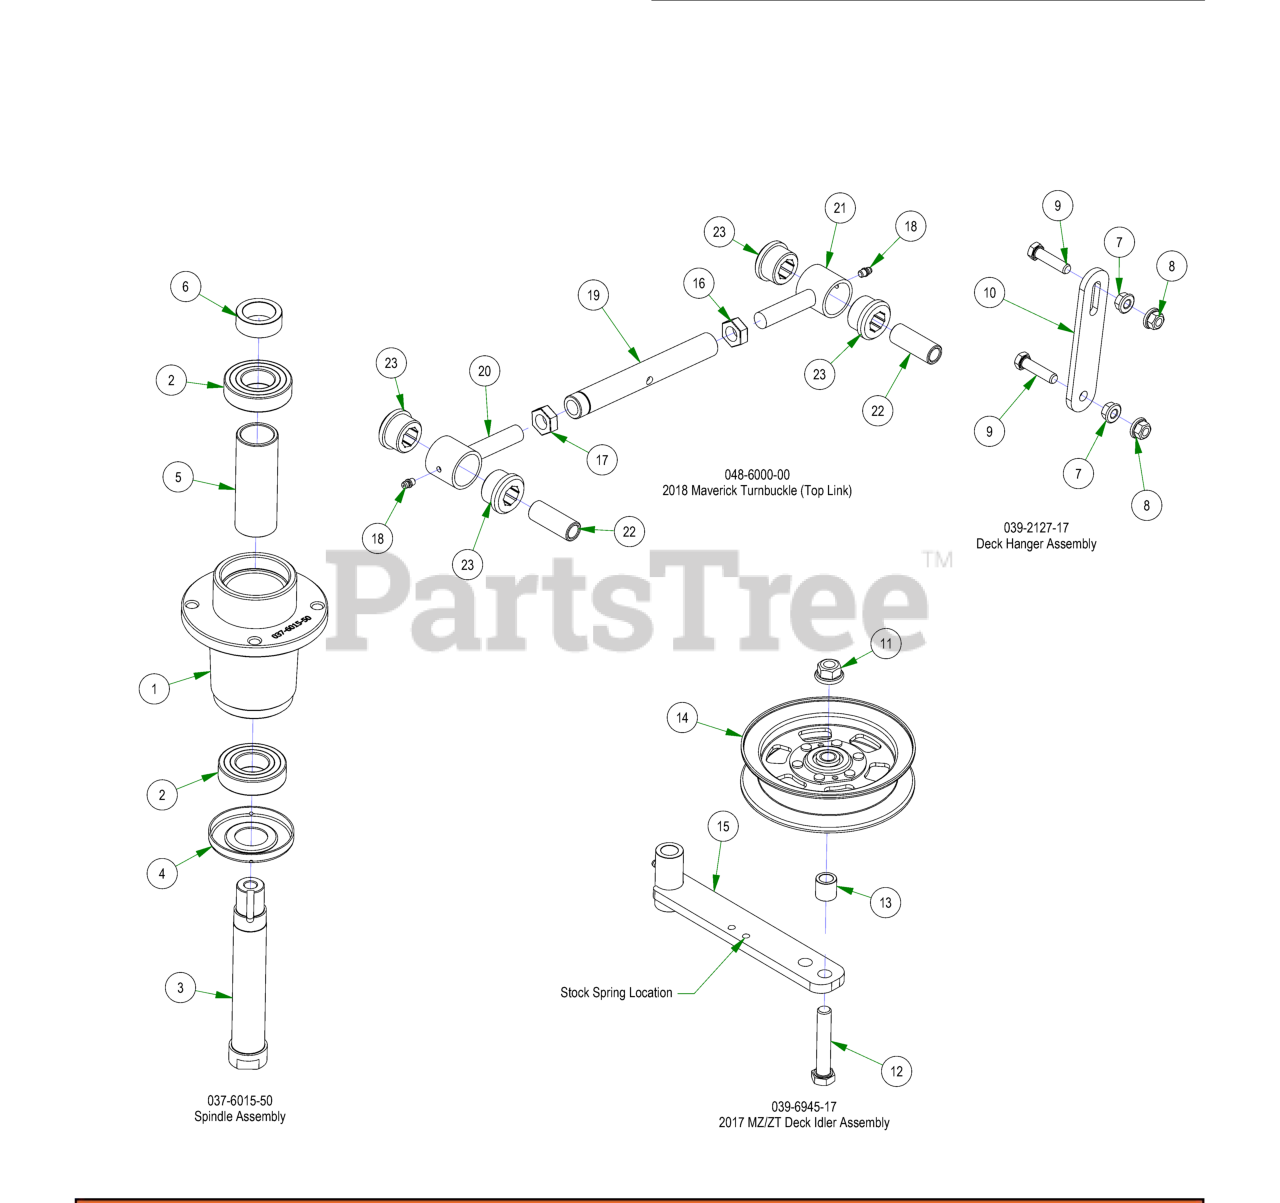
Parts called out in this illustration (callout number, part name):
1	Spindle Housing
2	Bearing - 6206
3	Spindle Shaft
4	Spindle Dust Cap
5	Spindle Spacer
6	Locking Collar w/ 1/4"-20 Set Screw
7	3/8-16 HEX SERRATED FLANGE NUT HARD/ZINC
8	3/8-16 NYLON INSERT FLANGE LOCKNUT (GR.F) ZINC
9	3/8-16 X 1-1/2 HEX CAP SCREW (GR.5) ZINC
10	2017 MZ/ZT Deck Hanger
11	1/2-13 NYLON INSERT FLANGE LOCKNUT ZINC
12	1/2-13 X 2-3/4 HEX CAP SCREW (GR.5) ZINC
13	Spacer 3/4 OD x 1/2 ID x 3\4 Length
14	5" Idler Pully
15	Deck Idler
16	NUT, 5/8-18
17	NUT, 5/8-18LH
18	1/4-28 Grease Fitting
19	2018 Maverick Toplink Body
20	2018 Maverick Bushing Retainer Left-Handed
21	2018 Maverick Bushing Retainer Right-Handed
22	2018 Maverick Bushing Sleeve
23	2018 Maverick Bushing
